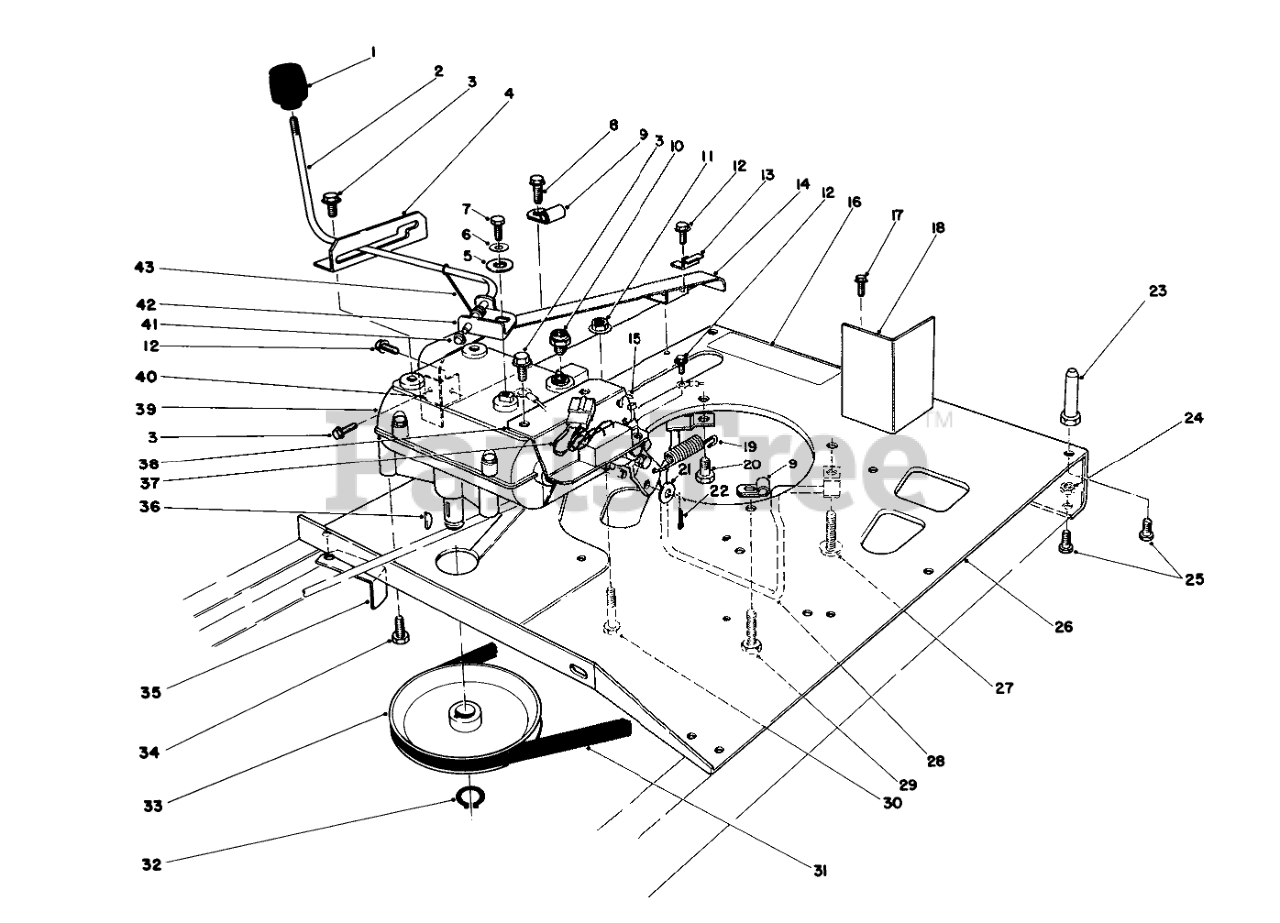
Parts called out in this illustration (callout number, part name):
2	SHIFT LEVER
3	SCREW-HWHTF
4	SHIFT LEVER GATE
5	WASHER-FLAT
6	WASHER-BELLEVILLE
7	SCREW-HH
8	SCREW-HHFTF
9	CLIP-FUEL LINE
10	NEUTRAL SWITCH
11	NUT-HF
12	SCREW
13	Clamp-Cable
14	Chain Guard
15	TIE-CABLE
16	DECAL
17	SCREW-HH
18	Baffle-Carb
19	SPRING-RETURN, BRAKE
20	Screw-HH
21	WASHER-FLAT
22	PIN-COTTER
23	PIN-MOUNTING, LOWER
24	NUT-LOCK, NI
25	SCREW-HH
26	Plate-Engine
27	SCREW-HWHTF
28	BELT GUIDE WA B
29	SCREW-HH
30	SCREW-HH
31	V-BELT
32	RING-SNAP, EXTERNAL
33	PULLEY
34	5/16-18 X 5/8 SEMS SC
35	TRANS BELT RET B
36	KEY-WOODRUFF
37	INTERLOCK MODULE
38	Mount Module
39	TRANSMISSION
40	CHAIN GUARD BRKT B
41	RETAINER-PUSH ON
42	SHIFT LEVER CLAMP
43	Spring-Shift Rod
